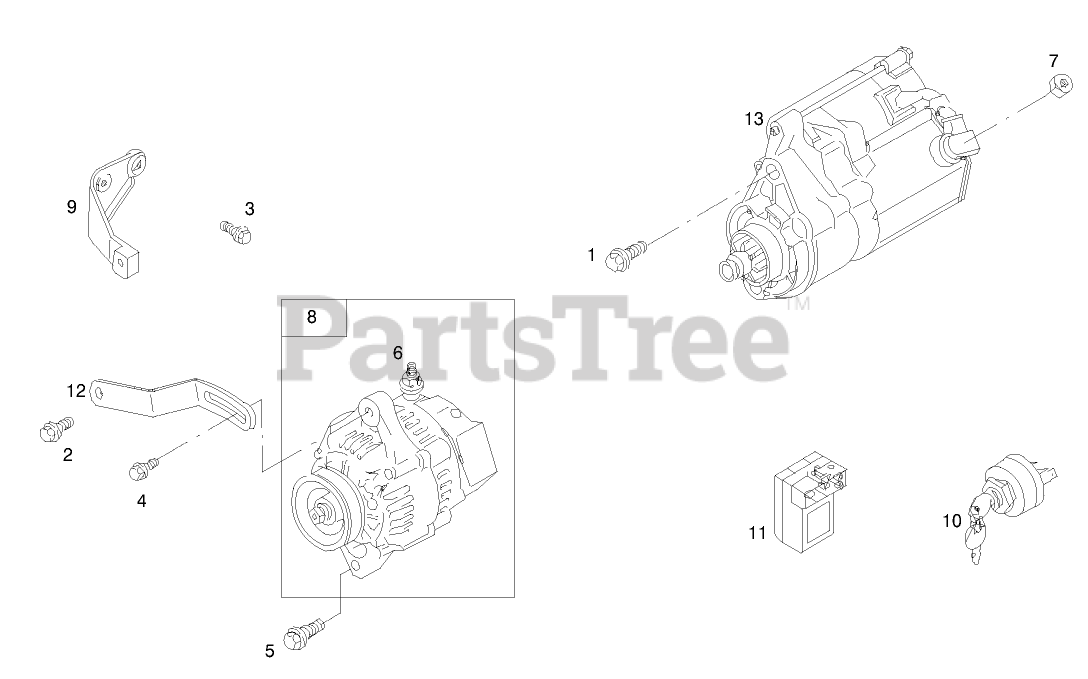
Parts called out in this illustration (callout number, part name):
1	SCREW-HEX
2	SCREW-HEX
3	SCREW-HEX
4	SCREW-HEX, METRIC
5	SCREW-HEX, METRIC
6	NUT-HEX, METRIC
7	NUT-HEX, METRIC
8	ALTERNATOR
9	BRACKET-SUPPORT
10	KEY SWITCH
12	BRACKET-ADJUSTING
